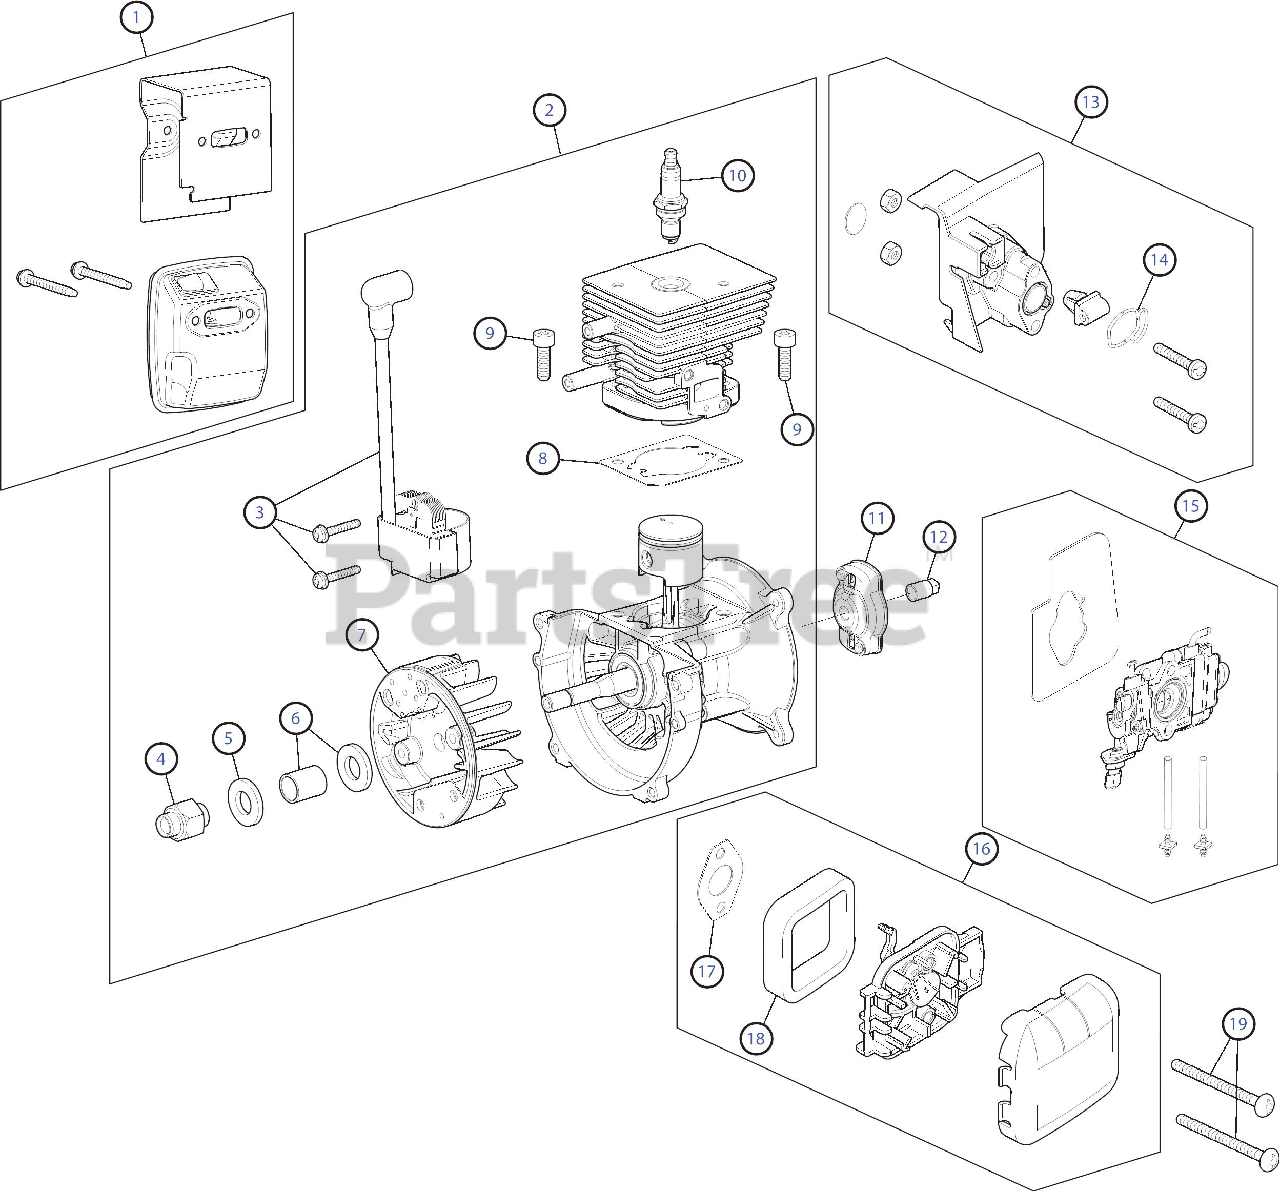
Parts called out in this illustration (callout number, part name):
1	Muffler Assembly
2	Shortblock Assembly (Incl. 3 - 10)
3	Module Assembly
4	Flywheel Adaptor
5	Washer
7	Flywheel Assembly
8	Cylinder Gasket
10	Spark Plug
11	Pawl Assembly
12	Electric Start Adaptor
13	Insulator Assembly (Incl. 14)
14	Insulator O-Ring
15	Carburetor Assembly
16	Air Cleaner Assembly (Incl. 17 and 18)
17	Carburetor Gasket
19	Air Cleaner Screw
